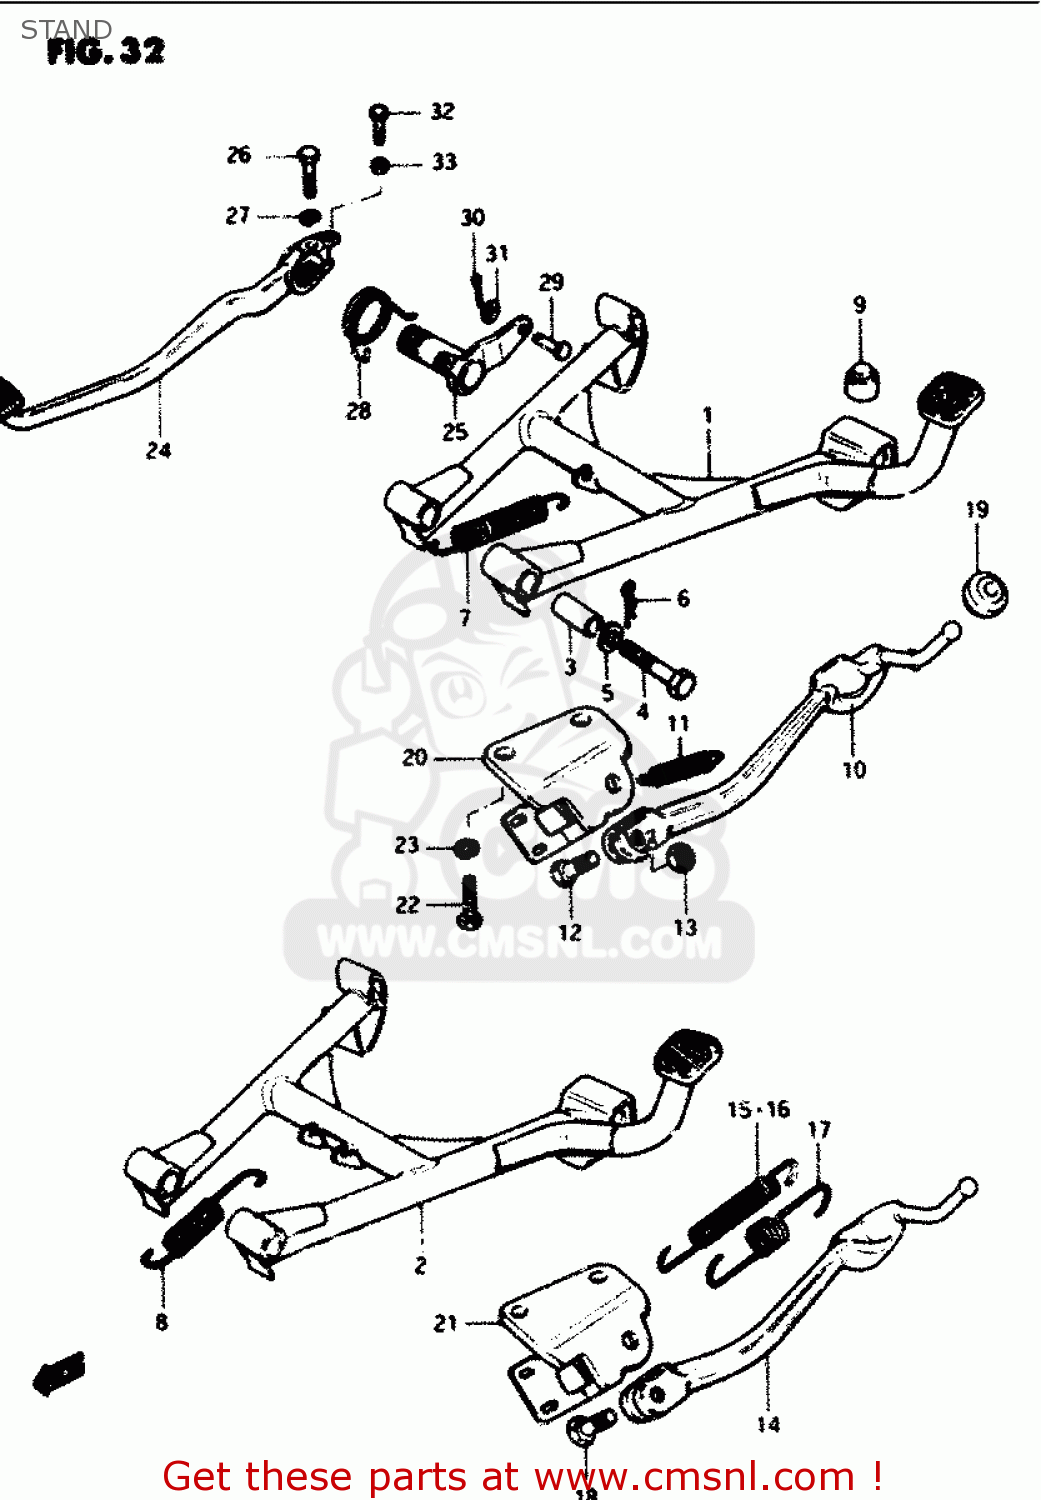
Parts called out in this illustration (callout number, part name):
1	STAND,CENTER
2	STAND, CENTER
3	SPACER(10X16X38.8)
4	BOLT
5	WASHER,LOCK,10
6	CLIP
7	SPRING
8	SPRING
9	CUSHION
10	STAND,PROP
11	SPRING
12	BOLT(10X30)
13	NUTM10X1.25X8
14	STAND, PROP
15	SPRING
16	SPRING
17	SPRING, OUTER
18	BOLT L:30
19	CUSHION
20	BRACKET,SIDE STAND
21	BRACKET
22	BOLT
23	WASHER,LOCK,10
24	PEDAL,BRAKE
25	ARM,BRAKE PEDAL ROD
26	BOLT
27	LOCK WASHER
28	SPRING
29	PIN
30	PIN
31	WASHER
32	BOLT
33	NUT 6MM
